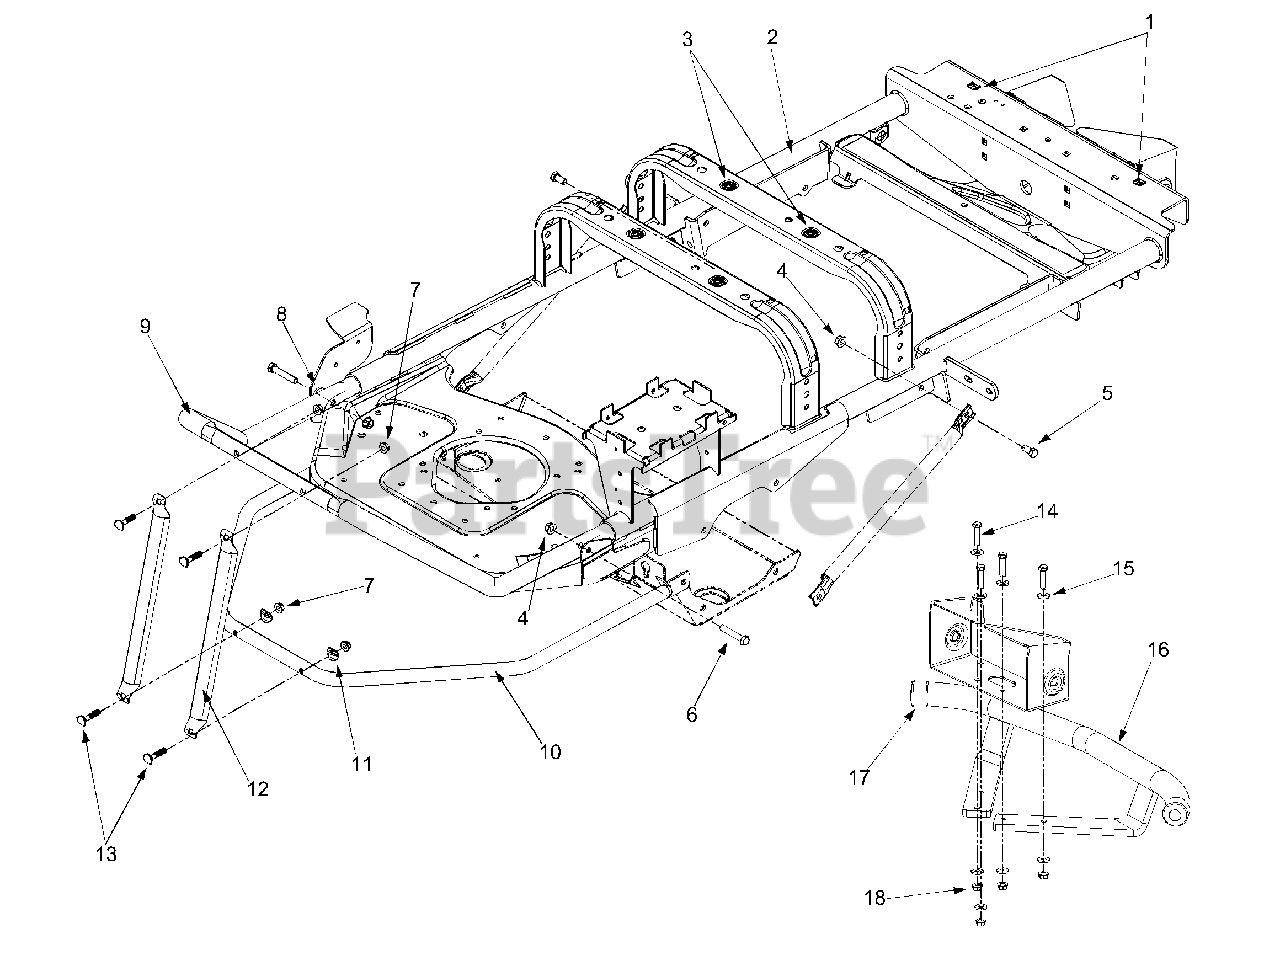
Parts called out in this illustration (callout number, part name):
1	Retainer Nut 3/8-16
4	Flange Lock Nut 3/8-16
5	Hex Cap Screw 3/8-16 x .75
6	Hex Cap Screw 3/8-16 x 2.0
7	Flange Lock Nut 5/16-18
8	Flat Washer .385 x 1.0 x .135
14	Hex Cap Screw 3/8-16 x 1.5
15	Flat Washer .406 ID x .875 OD
18	Flange Lock Nut 3/8-16
